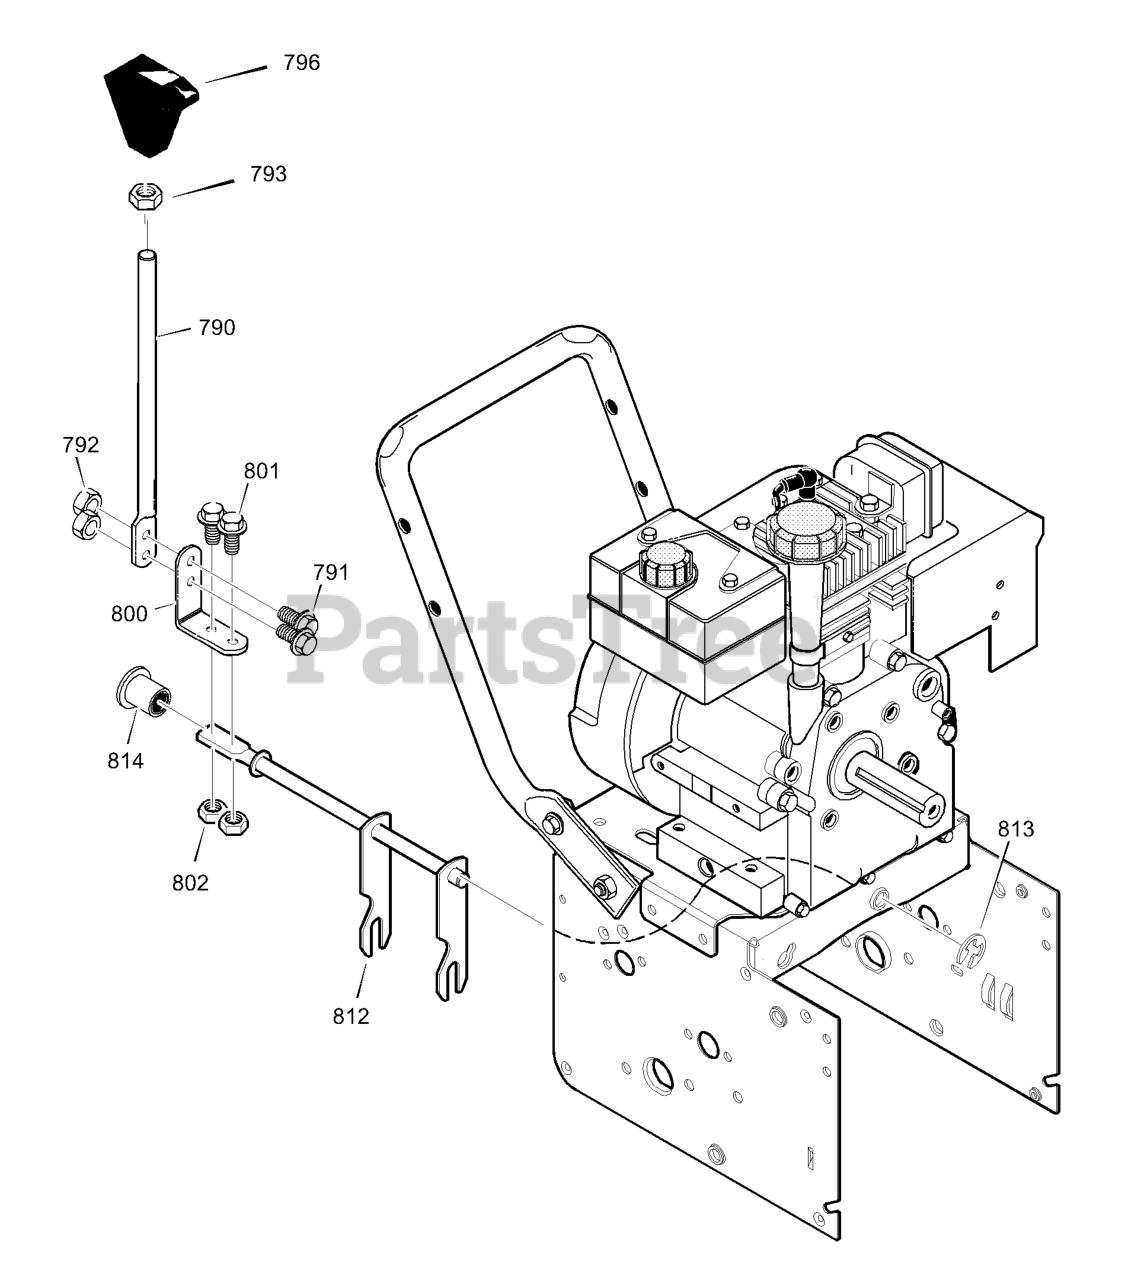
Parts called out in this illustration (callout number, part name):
790	ROD, SHIFT
791	SCREW, 1/4-20X.75
792	NUT, 1/4-20
793	NUT, 1/2-13 JAM
796	KNOB, SLIP
800	LEVER, SPRING
801	SCREW, 1/4-20X.75
802	NUT, 1/4-20
811	BEARING, FLANGED
812	ROD ASSY., SPEED SELECT
813	RETAINER, RING
